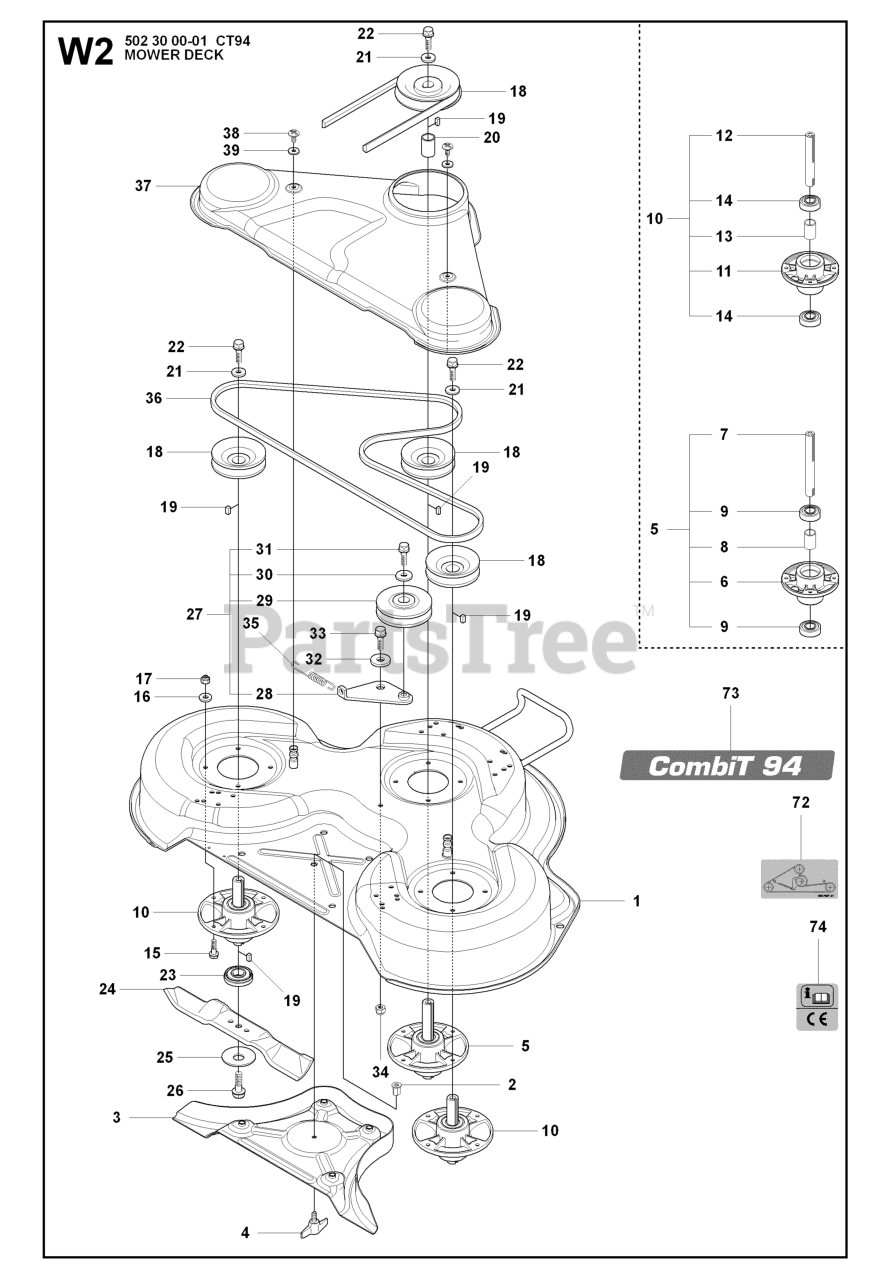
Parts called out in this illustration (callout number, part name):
42	LOCKNUT M8
48	LOCKNUT M8
50	PARALLEL ROD
54	BALL BEARING 6004-2RS1
55	PIVOT WHEELS
57	DECK ROLLER, FRONT
61	NUT
65	HUB CAP PIVOT WHEEL
67	LOCKNUT M8
71	LOCKNUT M8
